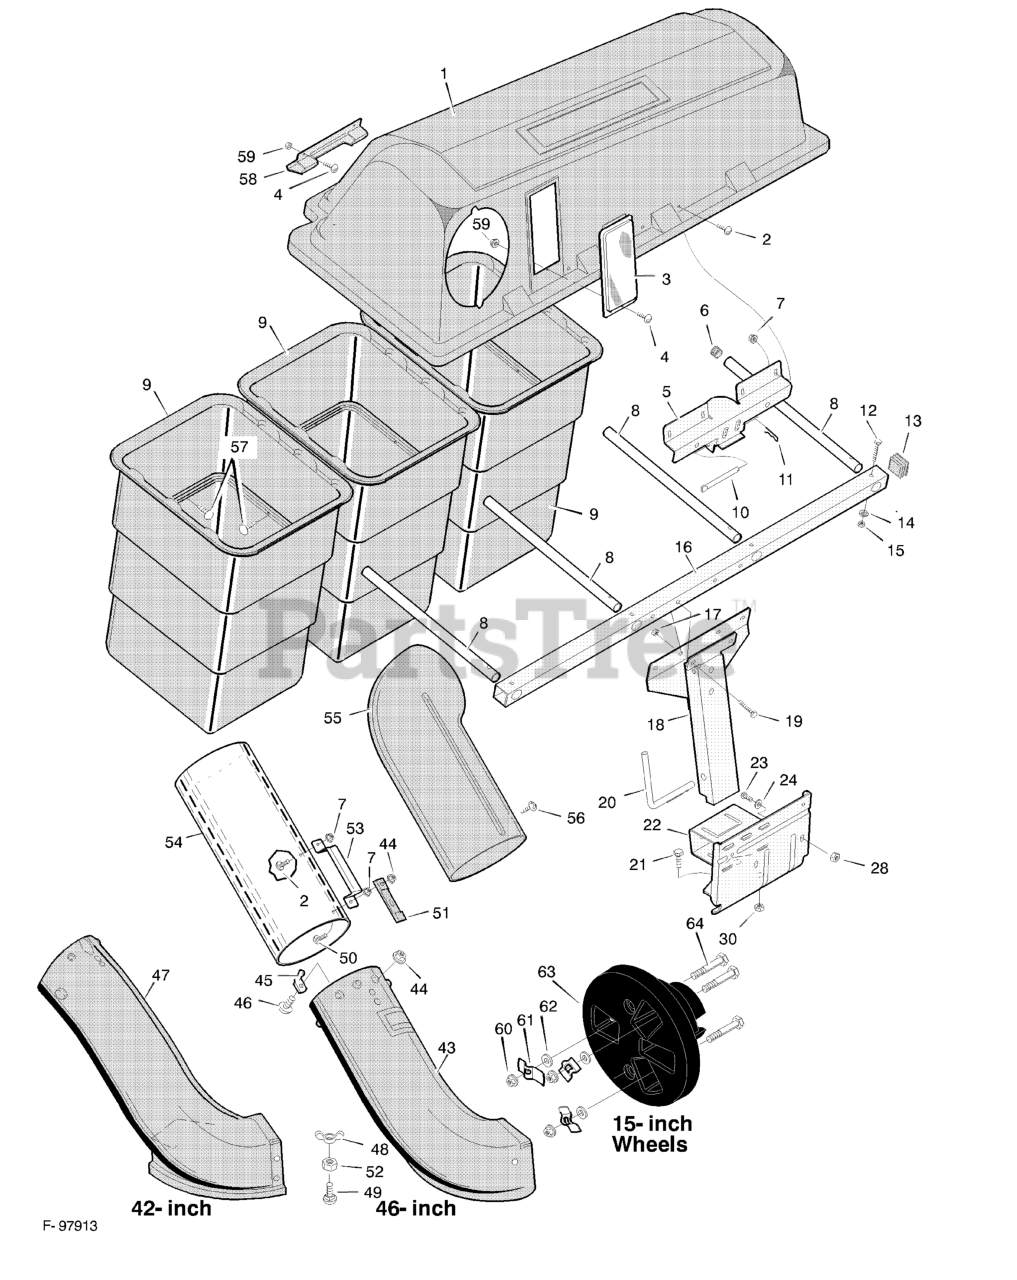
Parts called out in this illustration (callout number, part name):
1	Cover, Bagger
5	Hinge, Bracket
7	Nut, Hex
8	Tube, Container
9	Container
10	Pin, Cover Hinge
11	Pin, Hair
13	Plug
14	Lockwasher
16	Tube, Support
17	Nut
18	Assembly, Channel
20	Pin, Channel Mount
21	Bolt, Hex
22	Assembly, Bagger Mount
23	Bolt, Hex
28	Nut, Super Flange
30	Nut, Hex
43	Extension, Chute
44	Locknut, Flange
45	Pin, Latch
46	Bolt, Carriage
47	Extension, Chute
48	Wingnut
49	Bolt, Carriage
51	Latch, Rubber
53	HANDLE, Connect Tube
54	Tube, Connecting
57	Fastener, Panel
58	Handle, Plastic
59	Nut, Hex
60	Nut, Flange
61	Clip, Wheel
62	Retainer
63	Weight, Wheel
